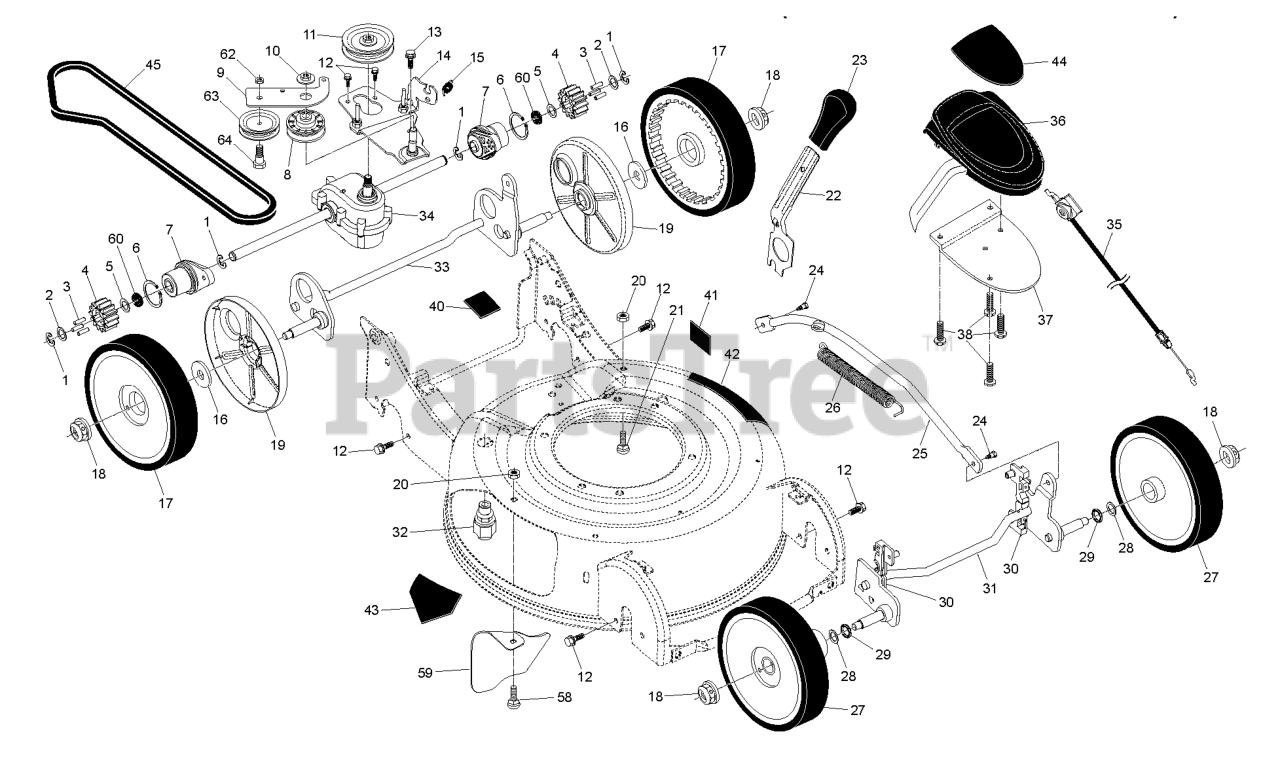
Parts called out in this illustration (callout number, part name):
1	E-RING 7/16 RE
2	THRUST WASHER
3	PAWL.DRIVE.ETCHED
4	PINION.DRIVE.WALK
6	RETAINING RING (2 2)(3 2)
8	PULLEY.IDLER.V-BELT
9	IDLER PULLEY
10	NUT.HEX.FLANGE.3/8-16.LOCKNUT
11	PULLEY.1.PIECE
13	SCREW 14-20 X 5/8
15	SPRING.RETURN
16	WASHER FLUT
17	WHEEL.8X1.75.H3SPK.RAD3.GY.BU3
18	NUT.HEX.FLANGE.3/8-16.LO(3 2)
19	COVER.DUST.WHEEL
20	NUT, HEX
21	BOLT.CARRIAGE.1/4-20 X 7/8
24	SHOULDER BOLT SEMI GIMLET PT.
26	SPRING EXTENSION
27	WHEEL & TIRES ASSY, FRONT
28	WASHER.FLAT.1/2
29	O-RING..070X.487.NEOPRENE
30	BUSHING.FRONT.TORQUE.S
36	CONTROL.DR.HV.RGD.GRY/BLU.45CM
37	BRACKET.DRIVE.CONTROL.MOUNT.BL
38	SCREW, PHILLIPS HEAD 10 X 5/8
43	DECAL.INTERNATIONL.CUTFINGER
44	Decal, Drive Control
